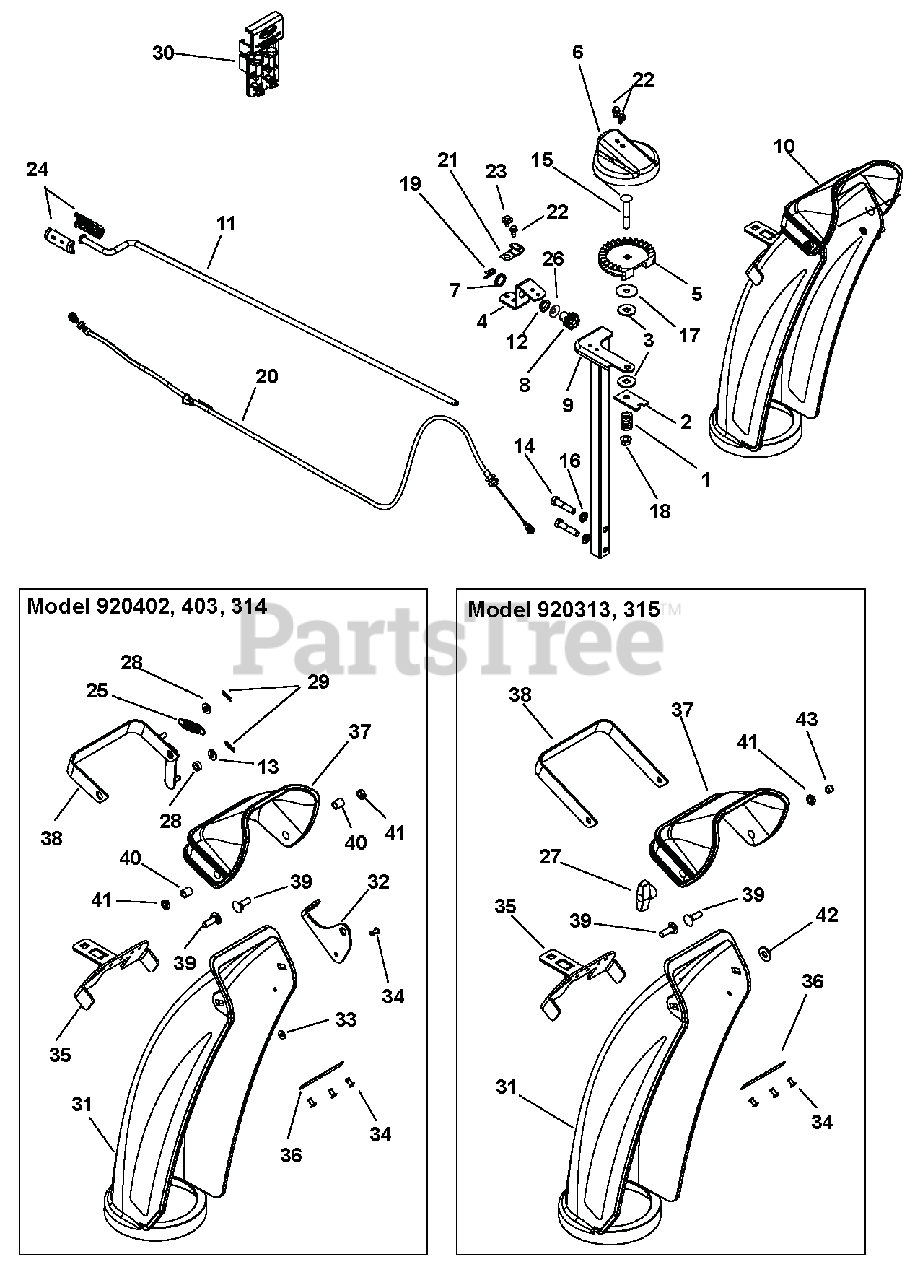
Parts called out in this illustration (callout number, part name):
1	SG-COMP .187X.56X1.62
2	PLATE, FRICTION
3	FRICTION WASHER
4	BRACKET, PINION GEAR
5	CHUTE GEAR
6	GEAR COVER
7	PUSHNUT .625
8	PINION GEAR W/BRACKET
9	CHUTE PEDESTAL, TALL COMPACT
10	CHUTE, REMOTE DISCHARGE W/CAP
10	CHUTE, MANUAL DISCHARGE W/CAP
11	ROD, CHUTE CRANK, COMP&SNOTEK
12	BUSHING, POLYLINER-.63 SNAPIN
13	BSHG-SLV .265X.500X.219
14	@BLT-HEX .38-16X1.75 GR5 YWZC
15	@BLT-RDHDSQNK .38-16X2.50 G5YZ
16	@WSHR-LK .38X.094 REG YWZC
17	@WSHR-FL-STL .406X1.25X.10 ZC
18	@NUT-LK-TOP-FLG .38-16 YWZC
19	PIN, SPRING CLIP
20	CABLE, DEFLECTOR CAP SNO-TEK
21	J-CLAMP
22	SCR-TAP .25-20X.50 HWH TR YWZ
23	SCR-TAP .25-20X.50 LGHWH TR YZ
24	KNOB, CHUTE CRANK - SNAP BLK
25	SPRG, TENSION .052X.520X1.74
26	WSHR-THRST .625 X 1.0 X .03
27	KNOB, WING .31-18 UNC
28	@WSHR-FL-STL.281X.62X.065 YWZC
29	PIN-HAIR INT .06X.18X.77
30	HOLDER W SMALL SHEAR BOLT /NUT
31	CHUTE, PLASTIC DISCHARGE LONG
32	BRACKET, CABLE ANCHOR SNOTEK
33	WSHR-FL-STL .196X.500X.06 YZ
34	RIVET, #66 STEEL POP PD BLACK
35	CHUTE MOUNT BRACKET
36	PLATE,CHUTE MOUNT BACKING
37	DEFLECTOR CAP, PLASTIC
38	WELDMENT, DEFLECTOR CAP SNOTEK
38	HANDLE, MANUAL CHUTE CAP
39	BLT,RNHDRECSHNK .31-18X1.00
40	BSHG-SLV .330X.455X.550
41	@NUT-LK-CTR-JAM .31-18 YWZC
42	@WSHR-FL-STL.38X.875X.083 YWZC
43	CAP, END .281X.313
